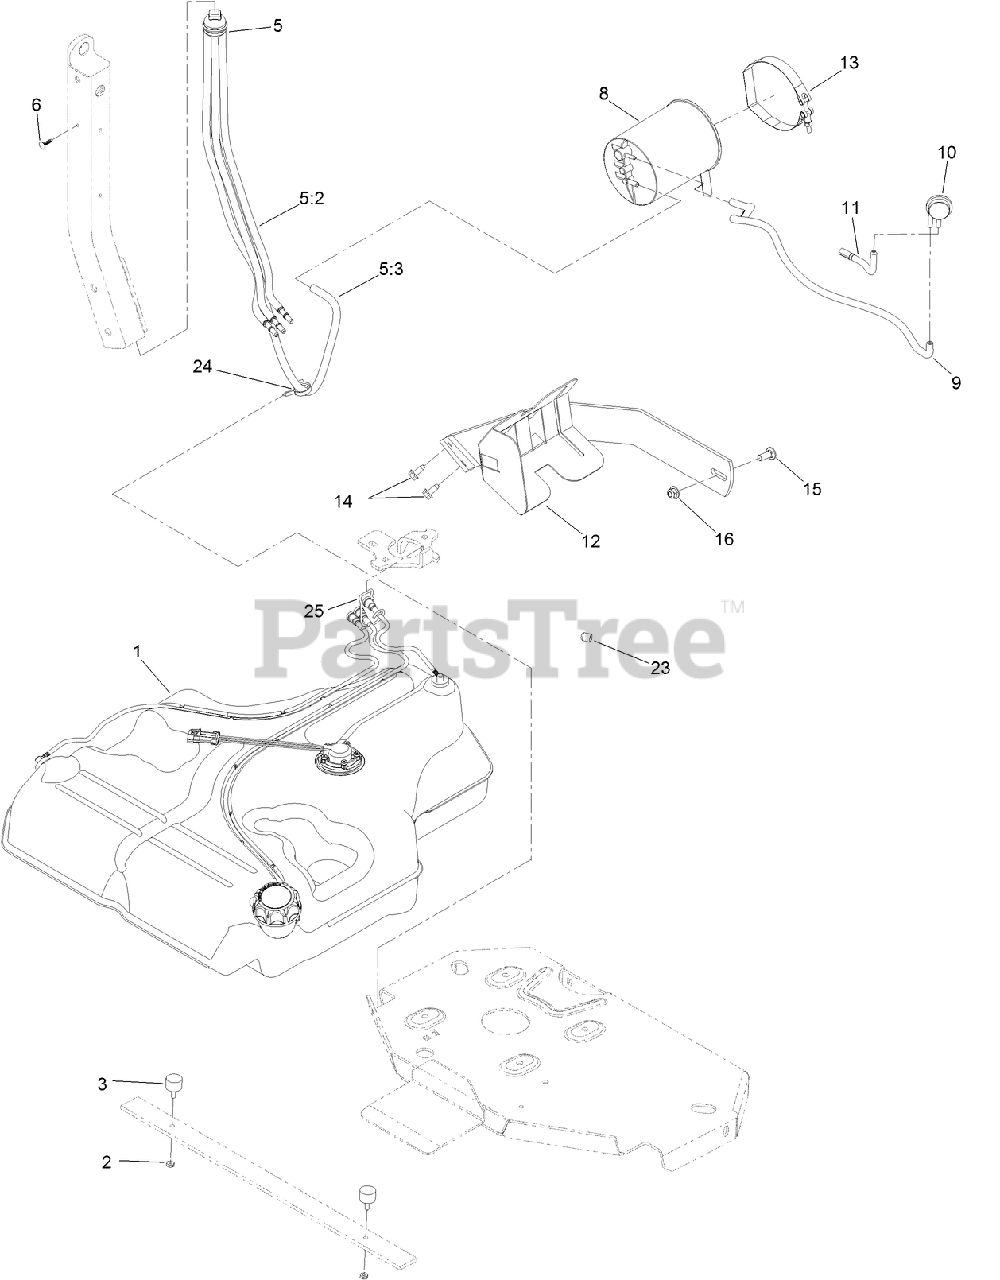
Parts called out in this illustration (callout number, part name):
1	FUEL TANK ASM
2	NUT-JAM
3	BUMPER
5	FUEL MANIFOLD VENT ASM
5:2	HOSE-FUEL
5:3	HOSE-FUEL
6	PLUG-PLASTIC
8	CANISTER-CARBON, 1200CC
9	HOSE-VENT, FORMED
10	VALVE-CHECK, VACUUM
11	HOSE-VENT, FORMED
12	MOUNT-CANISTER
13	CLAMP-T-BOLT
14	SCREW-HWHTF
15	SCREW-CARR
16	NUT-HF, NI
23	PLUG-PORT
24	CLAMP-HOSE
25	RETAINER-LINE, VAPOR
